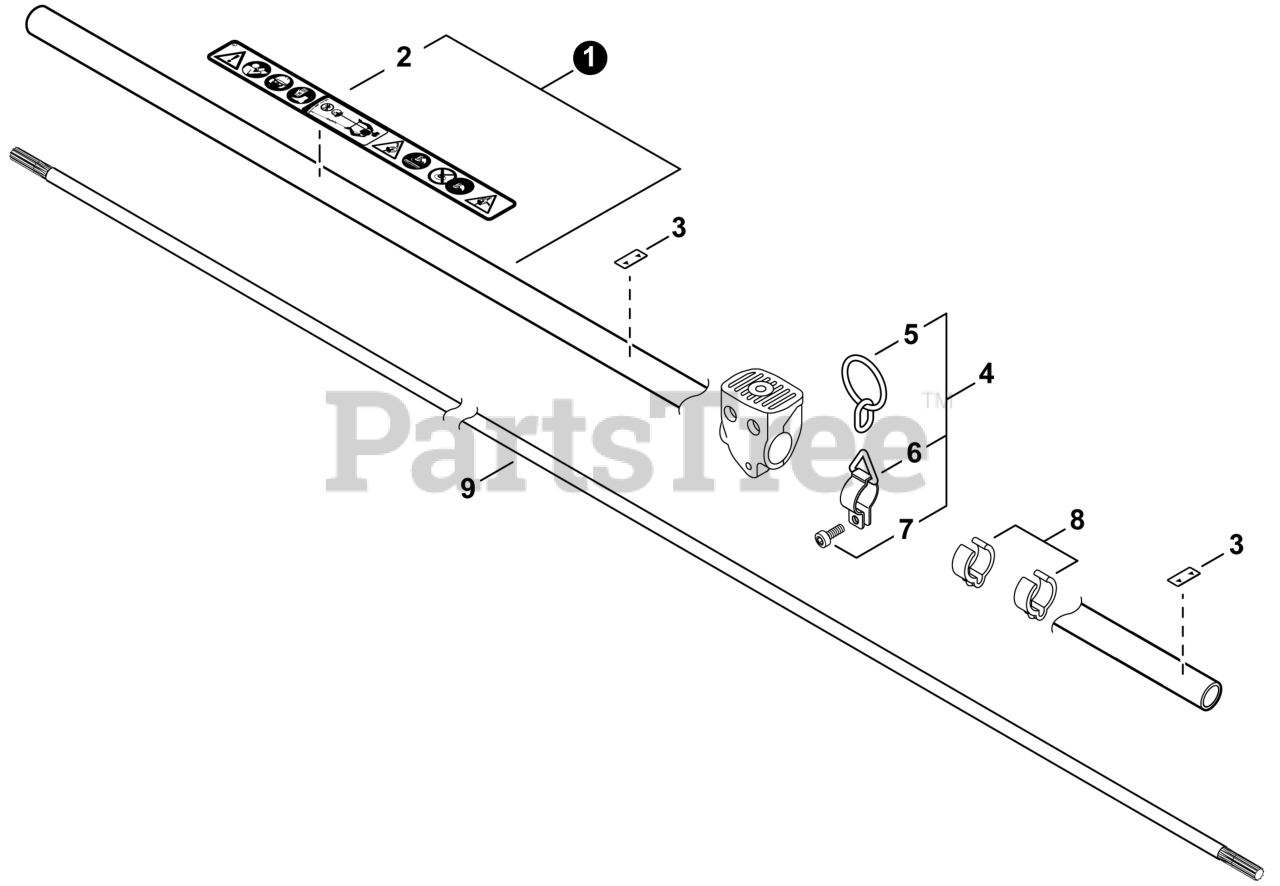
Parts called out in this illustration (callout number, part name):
1	MAIN PIPE ASSY
2	LABEL - CAUTION - ISO
3	LABEL - ALIGNMENT
4	HANGER ASSY, HARNESS
5	RING, HARNESS
6	HANGER, HARNESS
7	BOLT, TORX 5×12
8	CLIP, CABLE 28 MM
9	DRIVESHAFT
